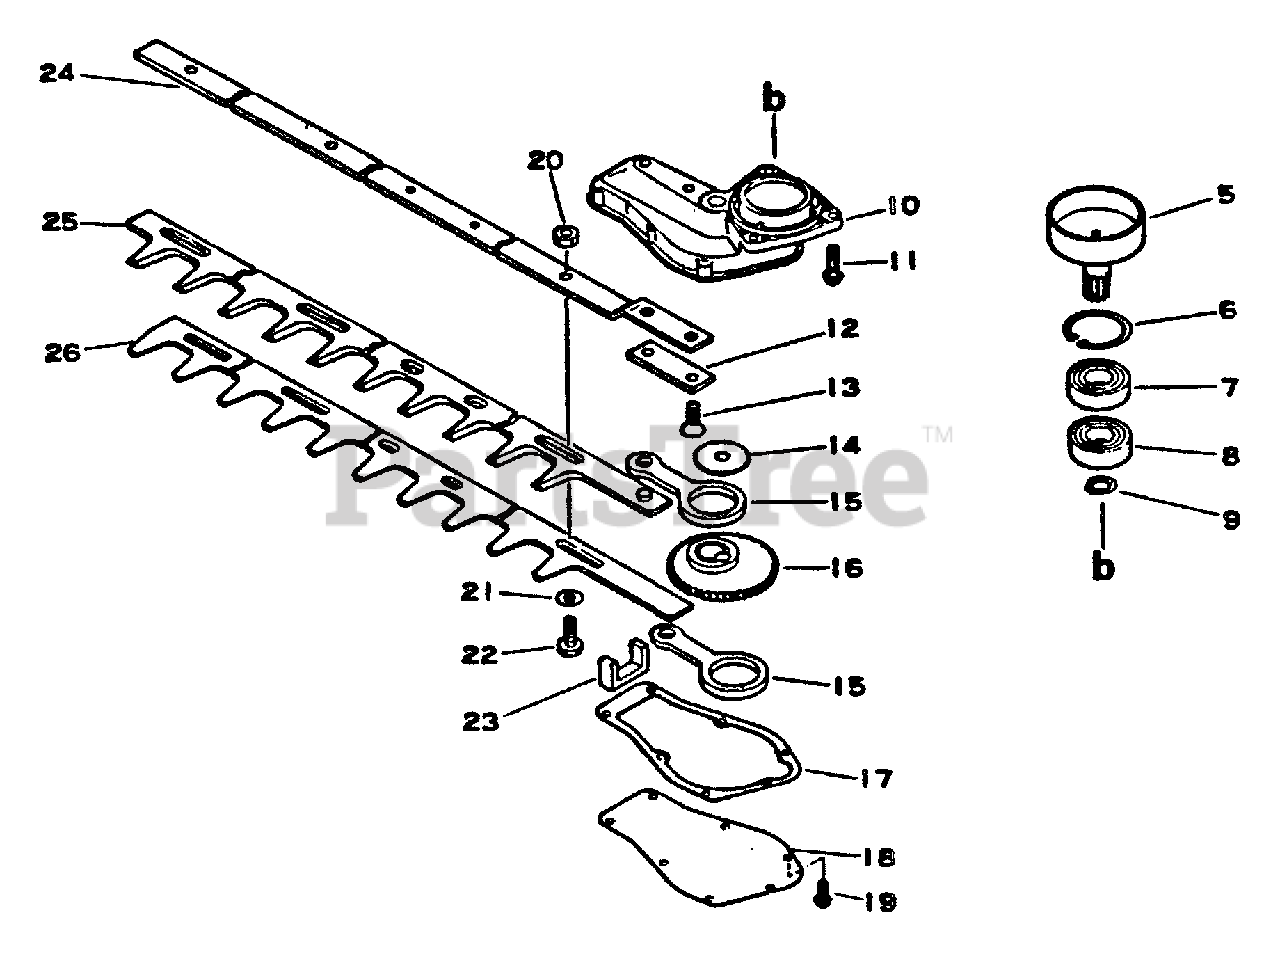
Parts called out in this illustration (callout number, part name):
5	DRUM, CLUTCH
6	RING, SNAP 35
7	BEARING, BALL 6202
8	BEARING, BALL 6202
9	RING, SNAP 14
10	CASE, GEAR
11	SCREW 5×20
12	PLATE, EYE
13	SCREW 6×18
15	ROD, CONNECTING
17	GASKET, GEAR CASE
18	LID, GEAR CASE
19	SCREW 4×10
20	LOCKNUT - 6
21	WASHER 6.5×15.5×0.6
22	BOLT, CUTTER
24	BAR, FRAME
24	TRIMMER BLADE SET
25	CUTTER, UPPER
26	CUTTER, LOWER
29	SPANNER 8×10
30	T-WRENCH 13×19×180
